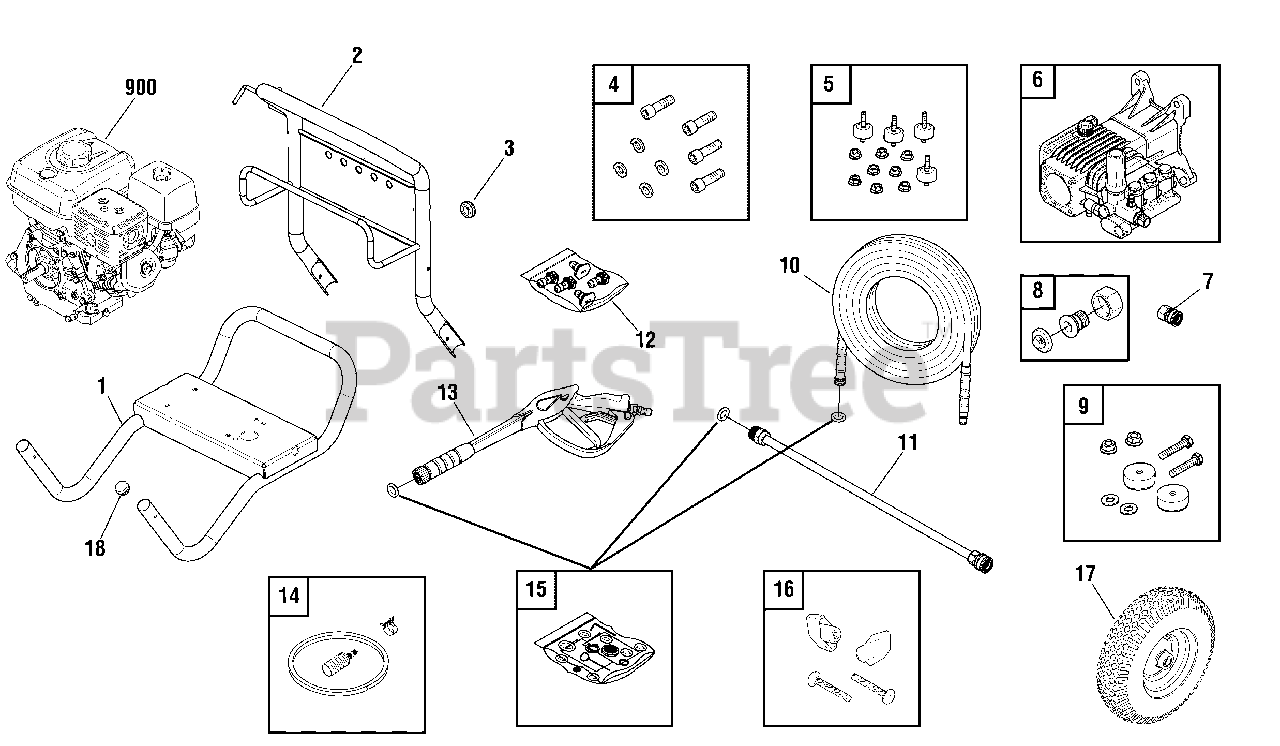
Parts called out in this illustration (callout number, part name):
4	KIT, Hardware, Engine Mounting
5	KIT, Hardware, Pump Mounting
7	FITTING
8	ADAPTER, Garden Hose
9	MOUNT, Vibration
11	EXTENSION, QC
12	KIT, QC Nozzles
16	KIT, Hardware, Handle
900	* ENGINE
